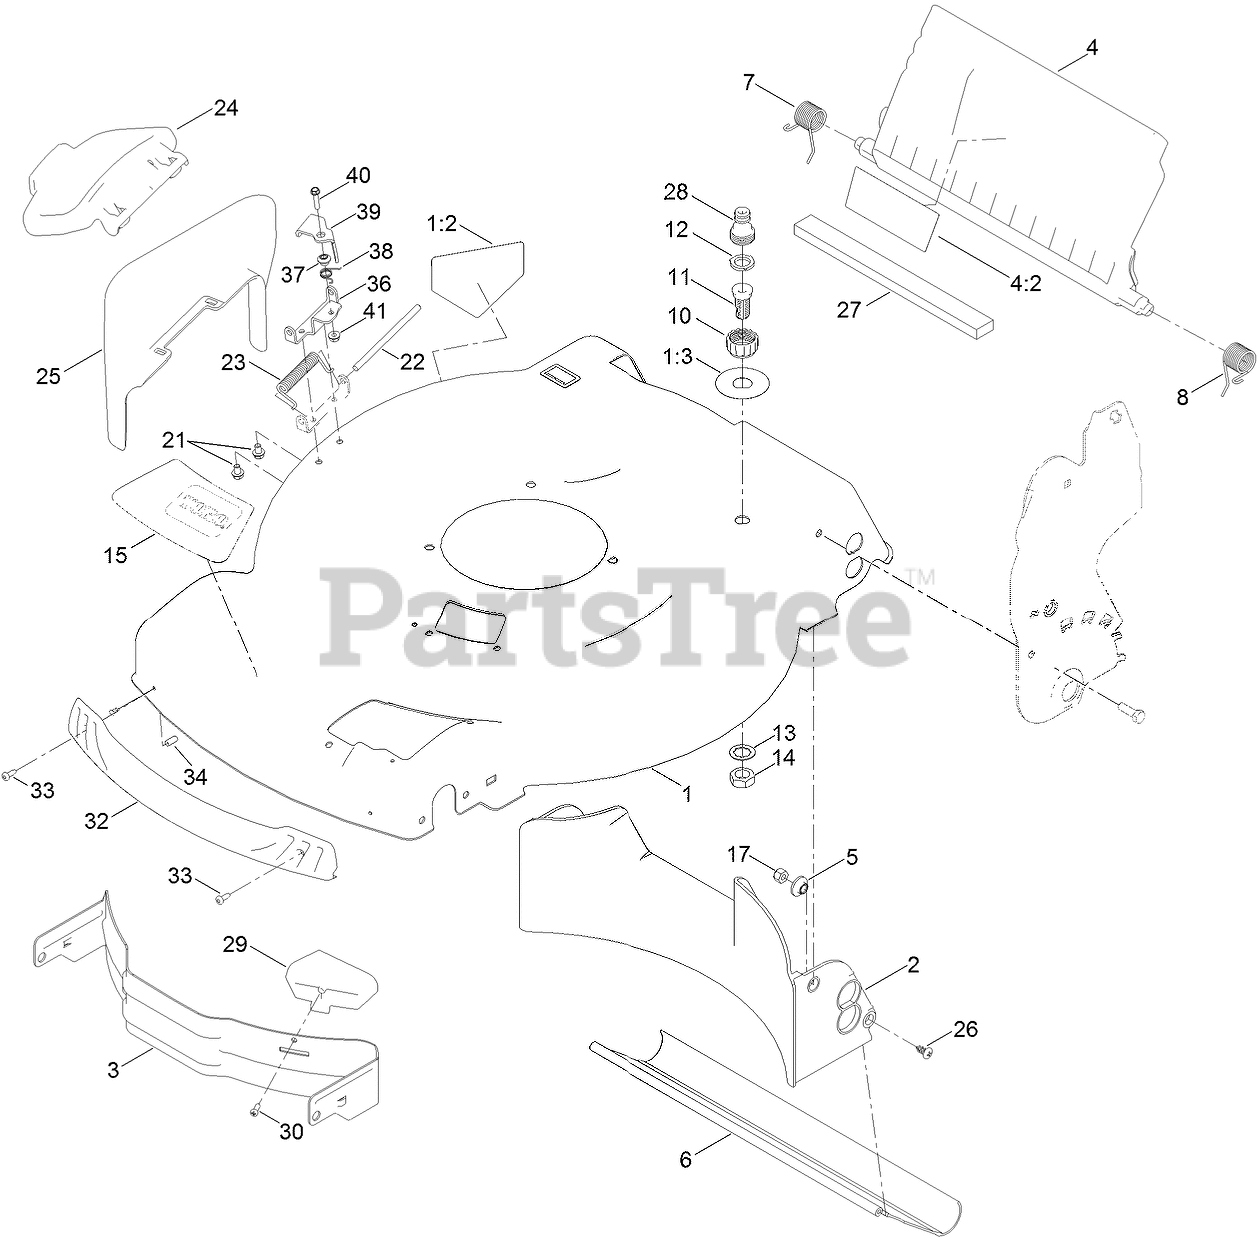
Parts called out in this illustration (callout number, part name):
1	HOUSING ASM
1:2	DECAL-DANGER
1:3	DECAL-QUICK WASH
2	BAFFLE-REAR
3	BAFFLE-FRONT
4	REAR DEFLECTOR ASM
4:2	DECAL-WARNING
5	WASHER-STEPPED, BAFFLE
6	SHIELD-TRAILING
7	SPRING-TORSION
8	SPRING-TORSION
10	COUPLING-HOSE, WASHOUT PORT
11	PORT-WASHOUT
12	WASHER-SEAL, WASHOUT PORT
13	WASHER-LOCK
14	NUT-JAM
15	DECAL-DECK
17	NUT-LOCK, NI
21	SCREW-HWH
23	SPRING-TORSION
24	DEFLECTOR-SIDE
25	CHUTE-DISCHARGE, SIDE
26	SCREW-PTH
27	FOAM-SEAL
28	ADAPTER-CONNECT, QUICK
29	KICKER-FRONT
30	SCREW-PPH
32	BUMPER
33	SCREW-FORMING, THREAD
34	CAP-PLUG
36	BRACKET-LOCKOUT
37	SPACER
38	SPRING-TORSION
39	LEVER-LOCKOUT
40	SCREW-HWH
41	NUT-LOCK, FLANGE
